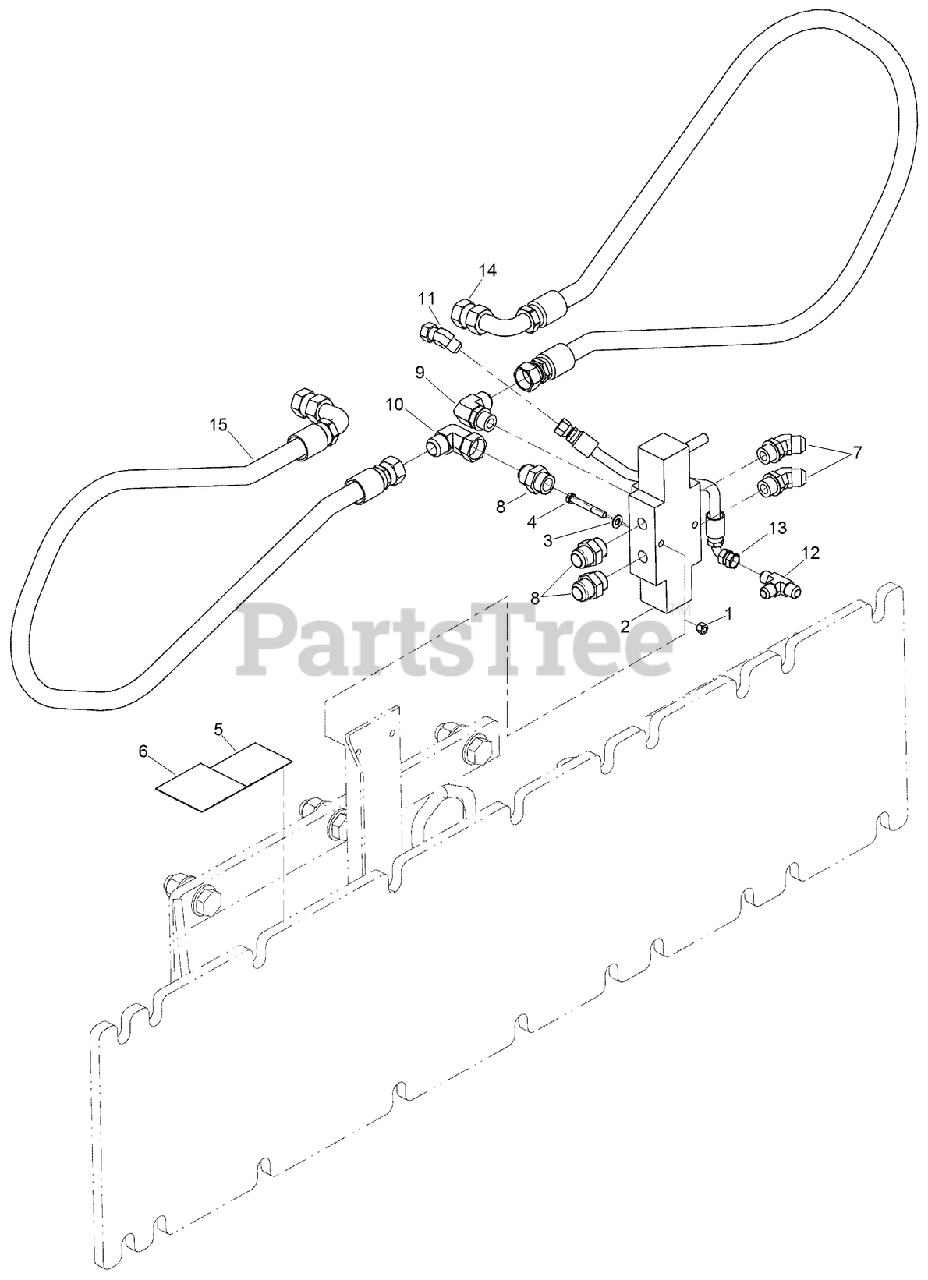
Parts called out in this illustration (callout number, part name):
1	NUT-HEX
2	VALVE - Selector
3	WASHER-0.406 x 0.812 x 0.065 in CST ZND
4	BOLT-HH
5	DECAL - Quad Selector Valve
6	DECAL - Quad Selector
7	ELBOW - 45 Adj 37FL 3/4 Tube
8	FITTING-STRAIGHT
9	ELBOW - 90 Adj 37FL 1.0 x 3/4 Tube
10	FITTING-ELBOW, 90
11	ELBOW - 45 Swivel, 37FL 5/8 Tube
12	TEE-10MJ x 10MJ x 10MJ
13	HOSE - 14 Inches
14	HOSE - 58 Inches
15	HOSE - 43 Inches
